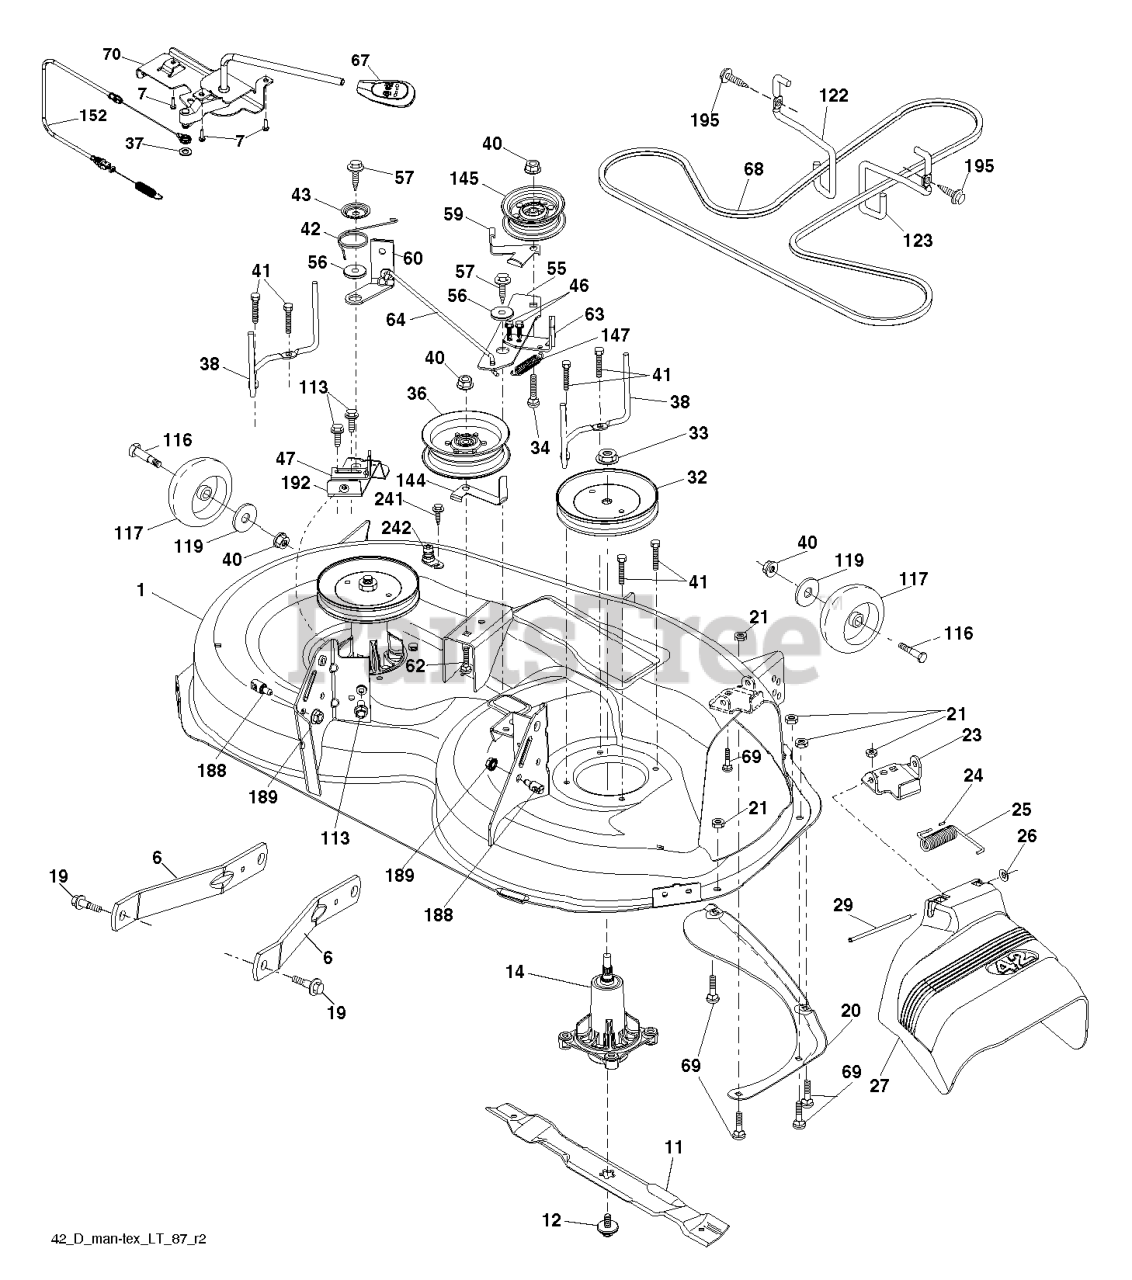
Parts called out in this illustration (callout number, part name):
1	Weldments
6	ARM.SUSPENSION.MOWER.R
11	42" HI-LIFT BLADE
12	SCREW.SEMS.7/16-20X1.HEX.HEAD
14	KIT.MANDREL.NONGREASE.TALL
19	BOLT.SHOULDER
20	BAFFLE.VORTEX
23	BRKT.DEFLECTOR.38"2005+
24	CAP-SLEEVE LT
25	SPRING.TORSION.DEFLECT
26	NUT PUSH M
27	SHIELD.DEFLECTOR.MOWER.42"BLAC
32	PULLEY.MANDREL.5.438.PD
34	GSPW Bolts
36	PULLEY.IDLER.2006
37	WASHER PLAIN WASHER 3/8 X 0.08
38	KEEPER.BLT.PNT.MNDRL.PULL.6.25
40	NUT LOCK FLG 3/8-16 UNC
41	BOLT.HEX.WASHR.HED.313-18X1.19
42	SPRING.TORSION.BRAKE
43	SRPING.TORSION.RETAINE
46	SCREW.1/4-20X5/8
47	BRKT.CLUTCH.CABLE
55	IDLER.ARM.42"
56	SPACER.RETAINER
57	SCREW 3/8-16X1
59	GUARD, BELT
60	ARM BRAKE MOWER
63	ARM BRAKE MOWER
64	LINKAGE.BRAKE.ASM.ZINC
67	HANDLE.CLUTCH.CABLE.LT
68	BELT.DECK.DRIVE.42"
70	CLUTCH.ASM.MANUAL.LT.PRED
113	BOLT.5/16HEX.WHS.HD
117	WHEEL.GAUGE.RALLY.NARROW
122	KEEPER BELT ENGINE LH
123	KEEPER BELT RH
144	KEEPER.BELT.MOWER
145	PULLEY.IDLER.48"PRIMARY
147	RETURN SPRING
152	CABLE.MECHANICAL.CLUTCH
188	STUD.W/"D"ANTI-ROTATION
192	BRKT.BRAKE.STAND.LH.
195	SCREW, 3/8-16X3/4
241	SCREW.TT.#10-32X.5.3/8.FLANGE
242	PORT.WASHOUT
